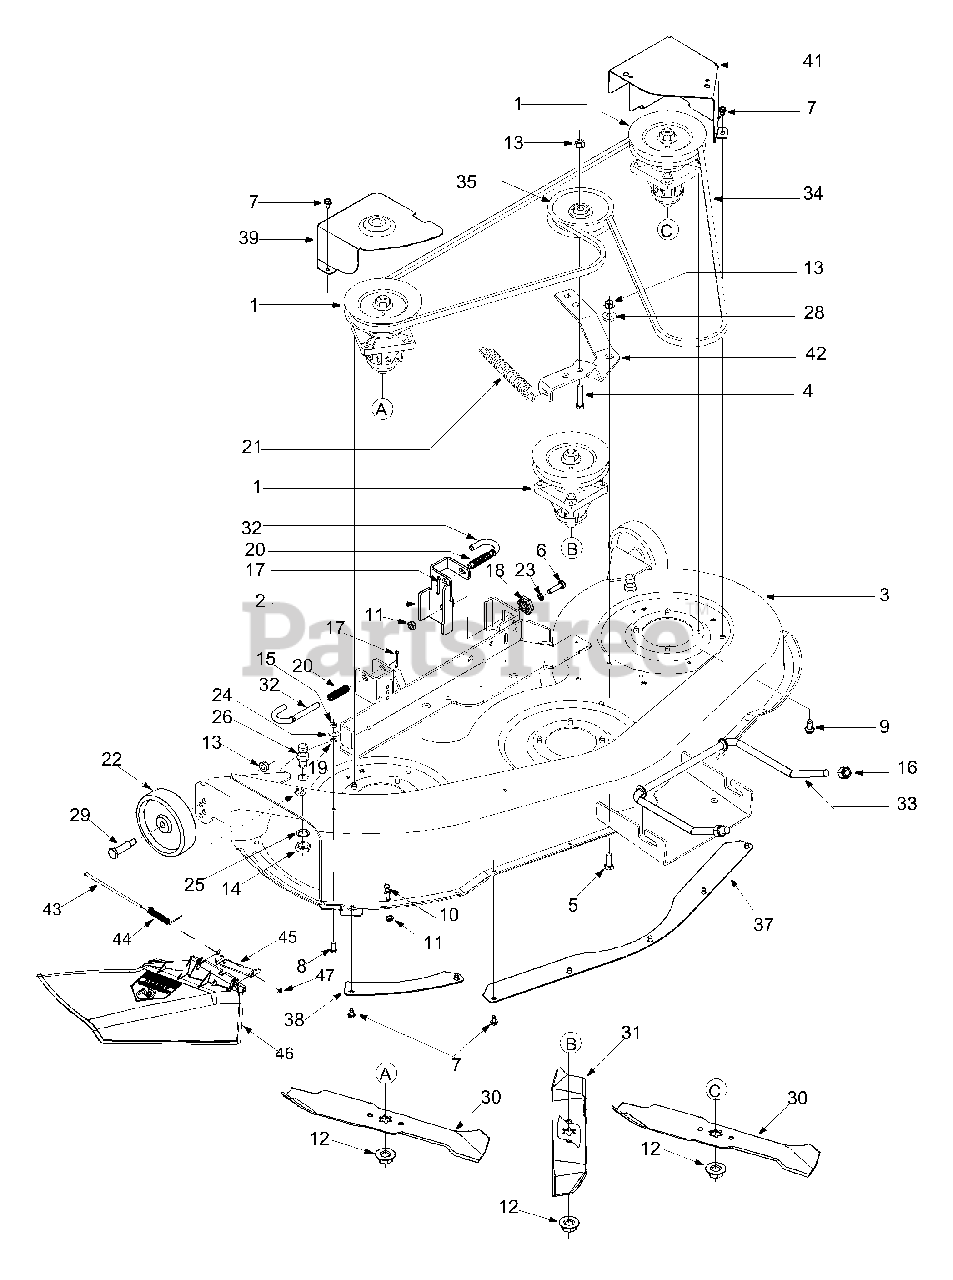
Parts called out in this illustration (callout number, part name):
1	Pulley-Spindle Assembly
4	Hex Bolt 3/8-16 x 1.75
5	Hex Bolt 3/8-16 x 1.0
6	Hex Bolt 5/16-18 x 1.25
7	TT Screw 1/4-20 x 0.5
8	Hex Bolt 1/4-20 x 0.620
9	LD Screw 5/16-18 x 0.75
10	Grasscatcher Pin
11	Lock Nut 1/4-20
13	Flanged Lock Nut 3/8-16
16	Hex Lock Nut 1/2-13
18	Gear: Deck Adjustment
20	Compression Spring
21	Extension Spring
23	Lock Washer
26	Nozzle
27	Grease
28	Shoulder Spacer
29	Shoulder Screw 3/8-16 x 1.5
30	Blade 16.28 Lg.: Three-in-One
31	Blade 14.88 Lg.: Three-in-One
32	Deck Release Handle
33	Deck Rod: Front Adjustment
34	V Belt
35	Idler Pulley
36	Danger Tag
43	Hinge Pin
44	Compression Spring
45	Mounting Bracket
46	Deflector: Discharge Chute
